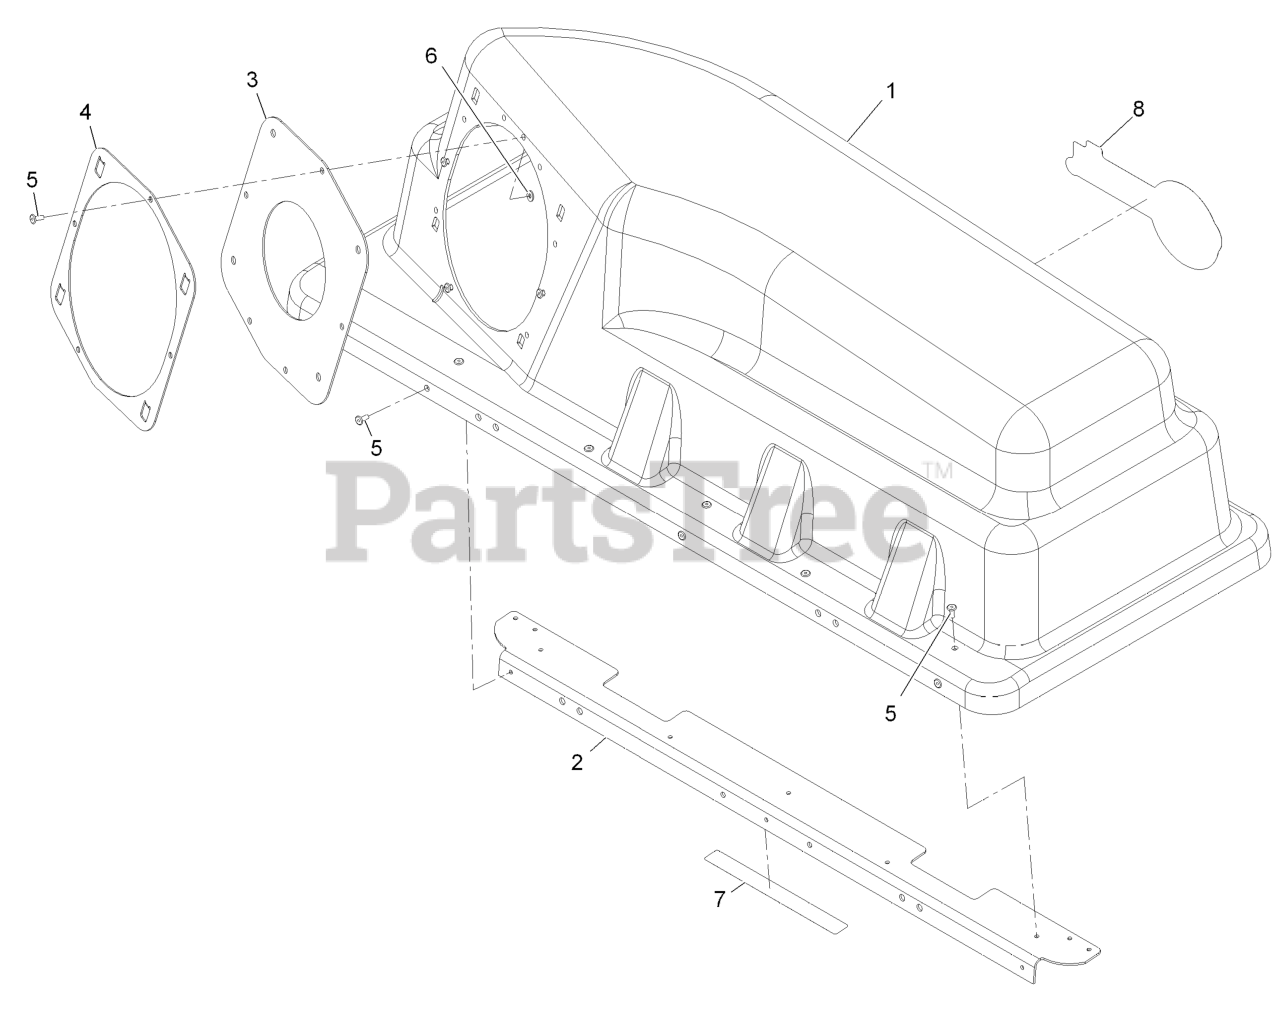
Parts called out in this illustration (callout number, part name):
1	TOP-BAGGER
2	STIFFENER-BAGGER, TOP
4	RING-RETAINER
5	RIVET-BLIND
6	WASHER-FLAT
7	DECAL-CAUTION, BAGGER
8	DECAL, EXMARK LOGO
